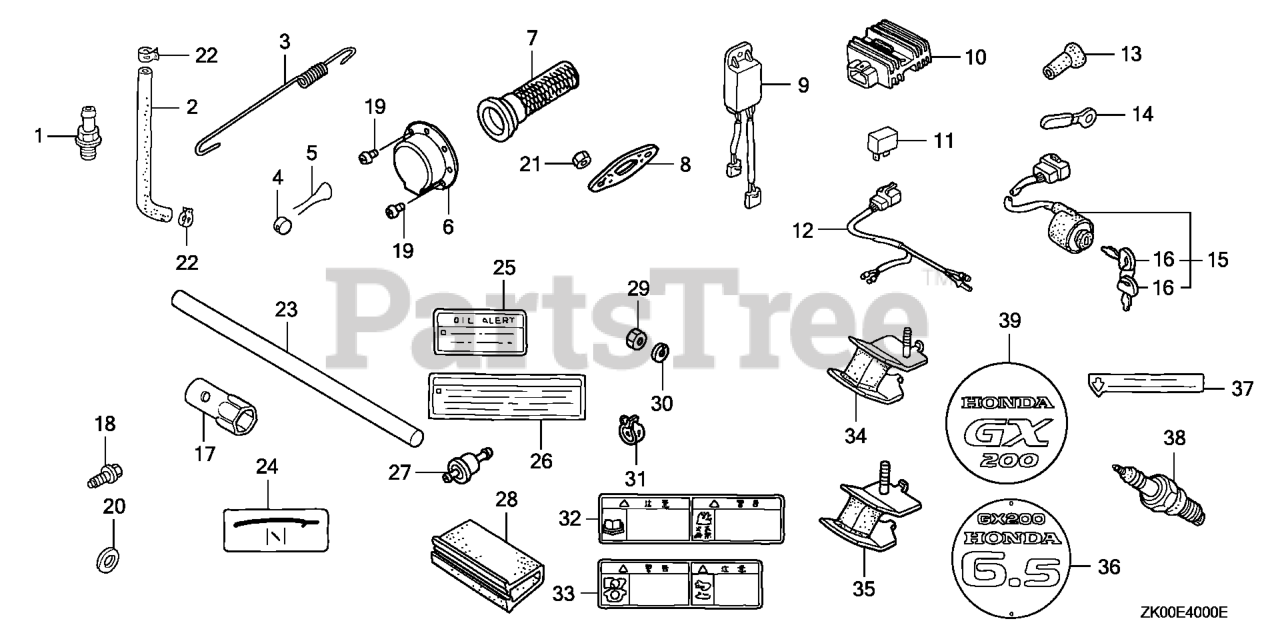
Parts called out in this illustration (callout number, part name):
3	SPRING, GOVERNOR
7	ARRESTER, SPARK (SILENT)
8	GASKET, MUFFLER
21	NUT, HEX. (8MM)
